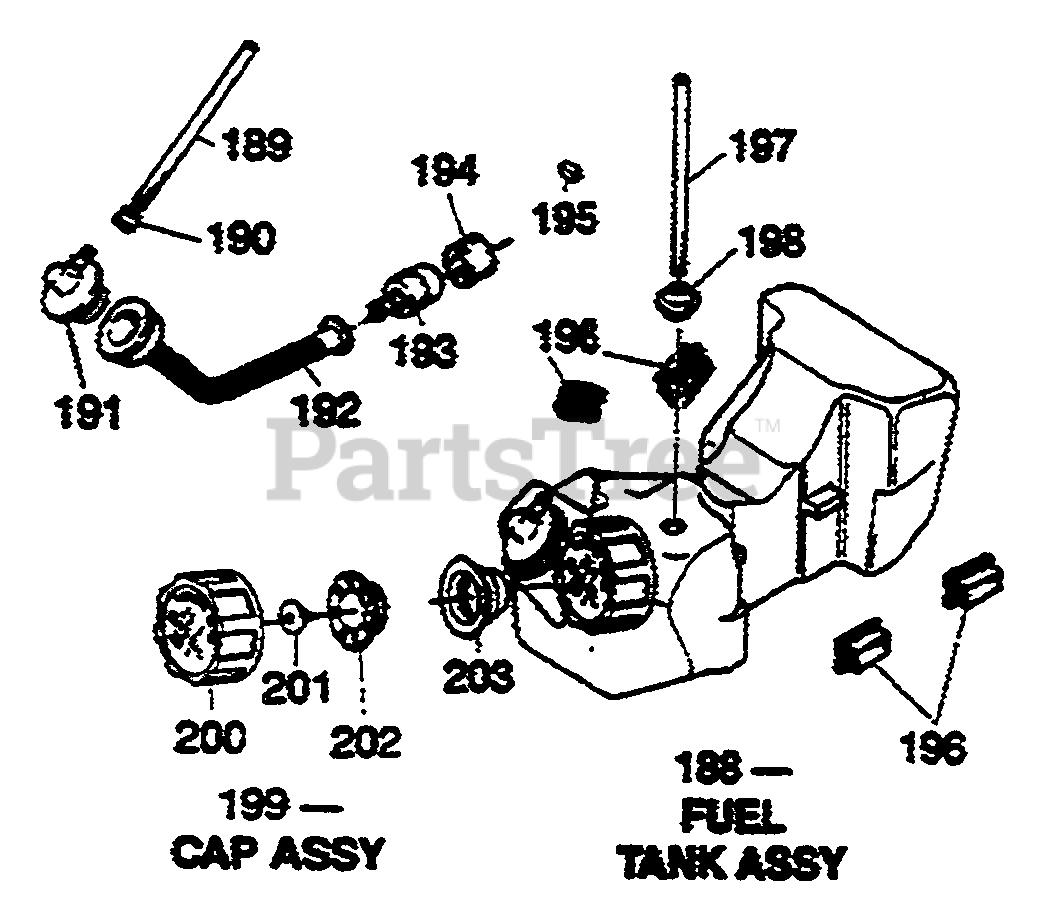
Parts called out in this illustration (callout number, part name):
188	FUEL TANK ASSY
189	TUBE,FUEL
192	HOSE,SUCTION
193	FILTER,FUEL
197	TUBE, FUEL
199	TANK CAP ASSY
201	VALVE, BREATHER
